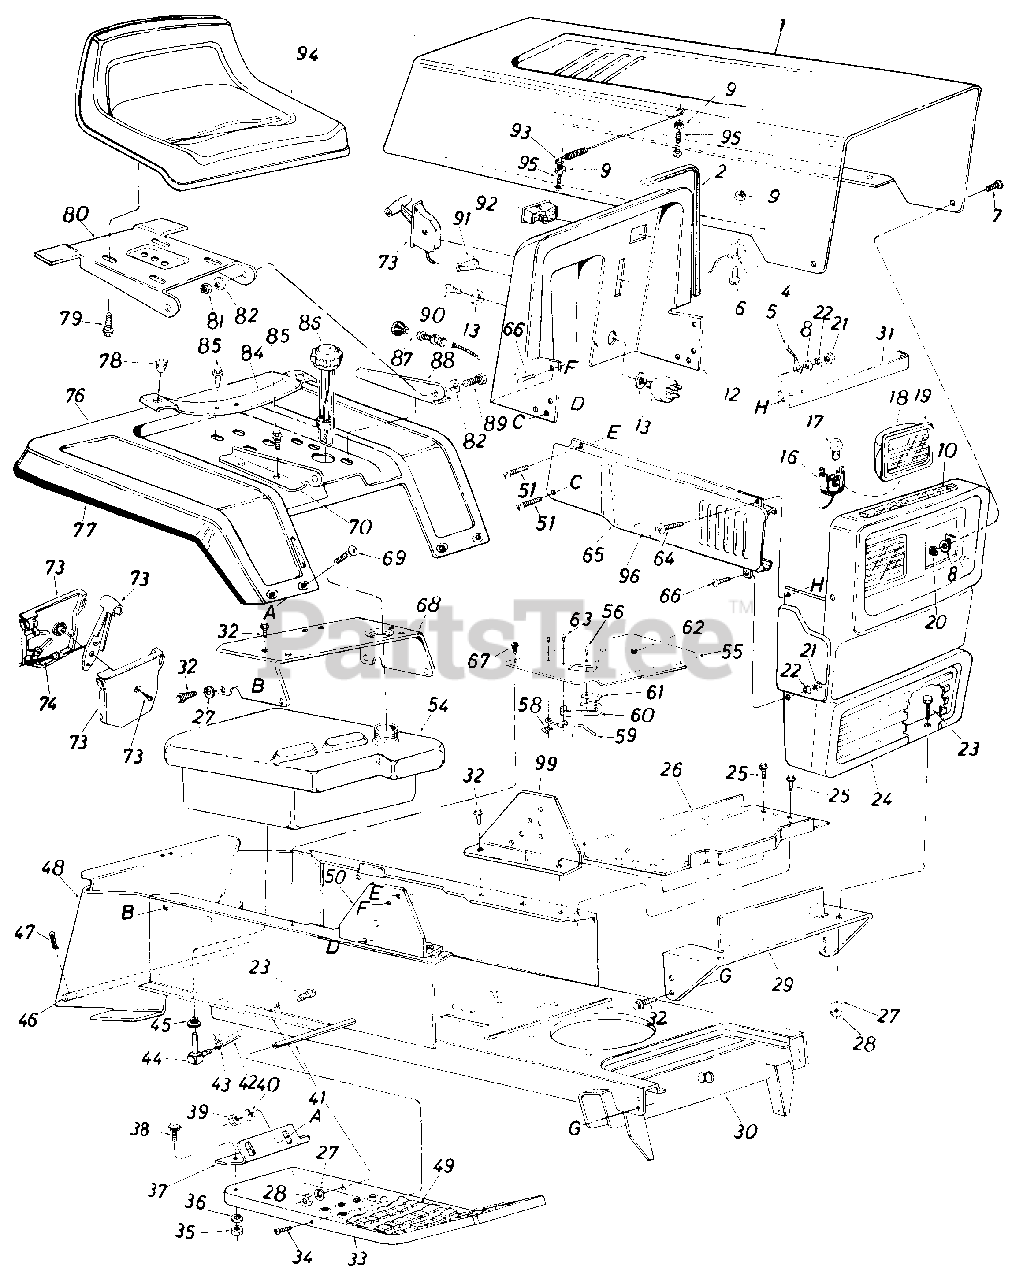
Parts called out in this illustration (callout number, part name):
1	Hood
2	Trim Strip 27" Lg.
4	Fl-Wash. .20" I.D. x .41" O.D.
5	Hood Stop
6	Truss Hd. Mach. Scr. #10-24 x .50" Lg.
7	Hex Bolt 1/4-20 x .62" Lg.
8	Fl-Wash. 1/4" I.D.
9	Hex Sem Nut #10-24 Thd.
10	Foam Strip 3/8 x 1" x 14"
12	Dash Ass'y.
13	Ignition Switch
16	Socket
17	Lamp
18	Headlight Housing
19	Lens
20	Hex L-Nut 1/4-20 Thd.
21	Hex Nut 1/4-20 Thd.
22	L-Wash. 1/4" I.D.
23	Hex Bolt 5/16-18 x .75" Lg.
24	Grille
25	Hex Wash. Hd. Scr. 1/4" x .50" Lg.
26	Battery Plate
27	L-Wash. 5/16" I.D.
28	Hex Nut 5/16-18 Thd.
29	Grille Mounting Bracket
30	Lower Frame Ass'y.
31	Tie Strap Grille/Side Panel
32	Hex Thd. Rolling Scr. 5/16-24 x .75" Lg.
33	Running Board R.H.
34	Truss Mach. Scr. 5/16-18 x .75" Lg.*
35	Hex Nut 5/16-18 Thd.
36	Bell-Wash. .34" I.D. x .87"
39	Hex Nut 1/4-20 Thd.
40	L-Wash. 1/4" I.D.
41	Running Board Rod
42	Fuel Line 40" Lg.
43	Hose Clamp 3/8
44	90ø Nipple
45	Bushing
46	Hitch Rod
47	Internal Cotterpin
48	Hitch Plate
49	Foot Pad
50	Dash Support Brk't. R.H.
51	Hex Wash. Hd. Tap Scr. 1/4 x .75" Lg.
54	Fuel Tank
55	Transmission Cover Ass'y.
56	Hex Self-Tap Scr. #8 x .38" Lg.
58	Speed Nut #10-24 U-Type
59	Shift Lever Spring
60	Switch Spring
61	Insulator Plate
62	Snap Bushing
63	Truss Mach. Scr. #10 x .50"
64	Truss Hd. Scr. 1/4-20 x .75"
65	Side Panel R.H.
66	Truss Mach. Scr. 1/4-20 x .50" Lg.
67	Truss Mach. "B" Tap Scr. #10 x .50" Lg.
68	Seat Mounting Channel
69	Carriage Bolt 1/4-20 x .50"
70	Seat Bracket R.H.
73	Throttle Control Box Ass'y.
74	Throttle Control Wire
78	Grommet
79	Hex Wash. Hd. AB-Tap Scr. 3/8 x .75" Lg.
80	Seat Pivot Bracket
81	Hex Cent. L-Nut 5/16-18 Thd.
82	Belleville Wash. .34" I.D. x .88" O.D.
84	Seat Spring
85	Hex Wash. Hd. Self-Tap Scr. 5/16-18 x .50" Lg.
86	Gas Cap w/Gauge
87	Choke Control Comp.
88	Seat Bracket L.H.
89	Hex Bolt 5/16-18 x .75" Lg.
90	Ignition Key
91	Light Switch
92	Ammeter
93	Hood Spring
94	Seat Ass'y.
95	Hex Screw #10-24 x 1.0" Lg.
96	Rubber Strip 1/2" Sq. x 21/2" Lg.
99	Dash Support Brk't. L.H.
